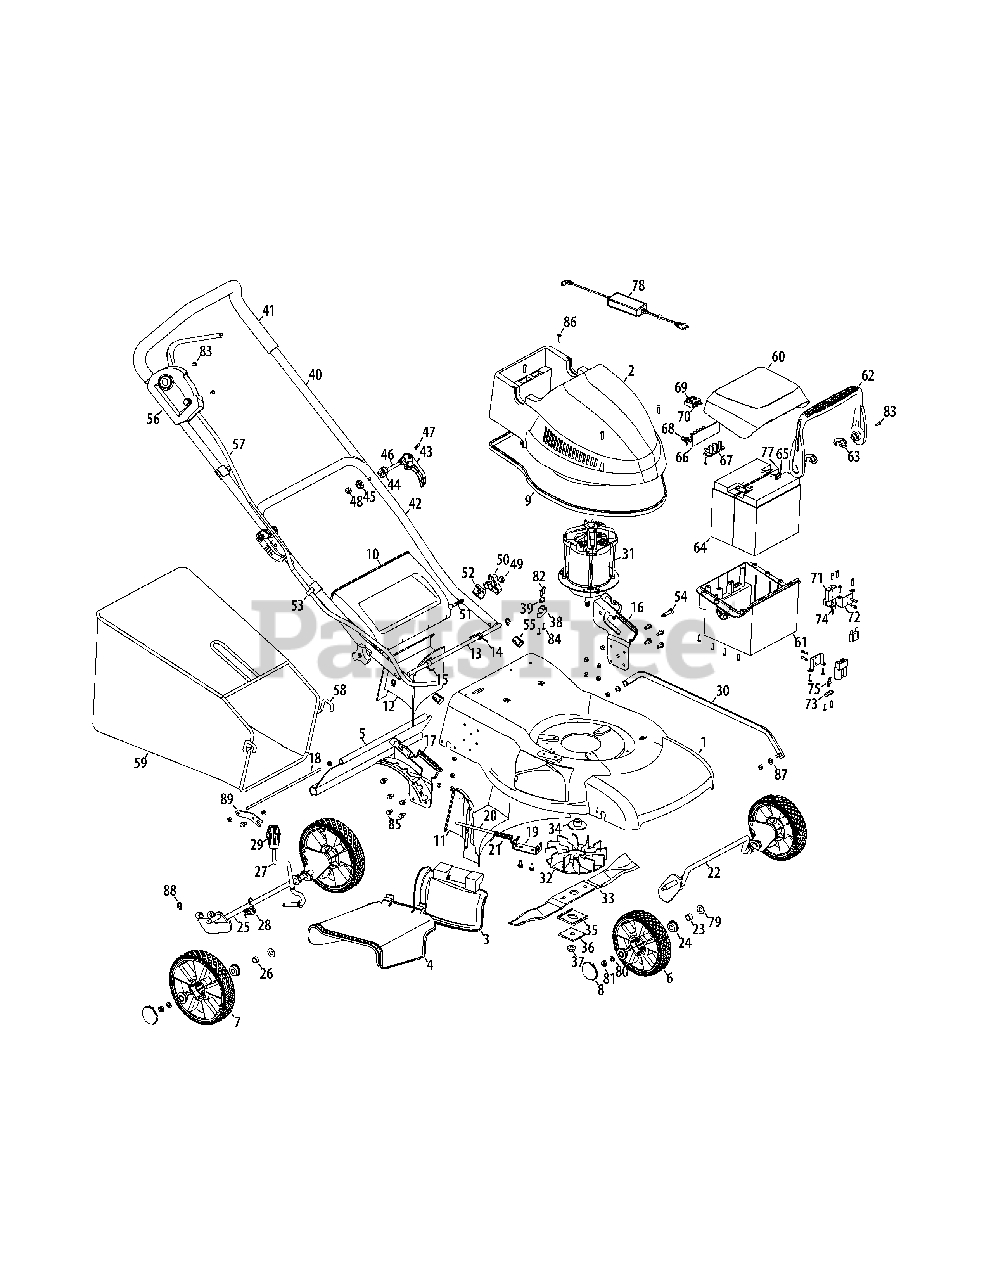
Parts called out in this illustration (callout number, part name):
2	Shroud
3	Side Discharge Door
4	Side Discharge Chute
5	Trail Shield
6	Front Wheel
7	Rear Wheel
8	Wheel Cap
9	Seal Line
10	Rear Door
11	Rear Baffle
12	Mulching Plug
13	Rear Shaft
14	Spring
15	Spring
16	Left Bracket
17	Right Bracket
18	Trail Shield Pin
19	Side Discharge Bracket
20	Side Discharge Pin
21	Spring
22	Front Shaft Assembly
23	Front Shaft Bushing
24	Bearing
25	Rear Shaft Assembly
26	Rear Shaft Bushing
27	Handle Adjust
28	Handle Adjust Spring
29	Handle Adjust Knob
30	Link Bar
31	Motor
33	Blade
34	Flange
35	Washer
36	Washer
37	Blade Nut
38	Support
39	Strain Relief
40	Upper Handle
41	Handle Grip
42	Lower Handle
43	Quick Release
44	Washer
45	Quick Release Knob
46	M8 Screw
47	Quick Release Pin
48	M8 Nut
49	M6 Lock Nut
50	Wing Knob
52	Washer
53	Cord Clip
56	Switch Box
59	Grassbag
60	Battery Pack Cover
61	Battery Pack Housing
62	Handle
64	Battery
65	Connector
67	PCB Support
68	Connector
69	Safety Key
70	Key Connector
71	SA50 Connector
72	Supporter
73	Supporter
74	Connector
75	Connector
78	Charger
79	Washer
80	8mm Washer
81	M8 Nut
82	ST4.2x16 Screw
83	ST4.2x25 Screw
84	ST4.8x16 Screw
85	M6x12 Screw
86	M5 x 12 Screw
87	Washer
88	10mm Lock Ring
89	Support
